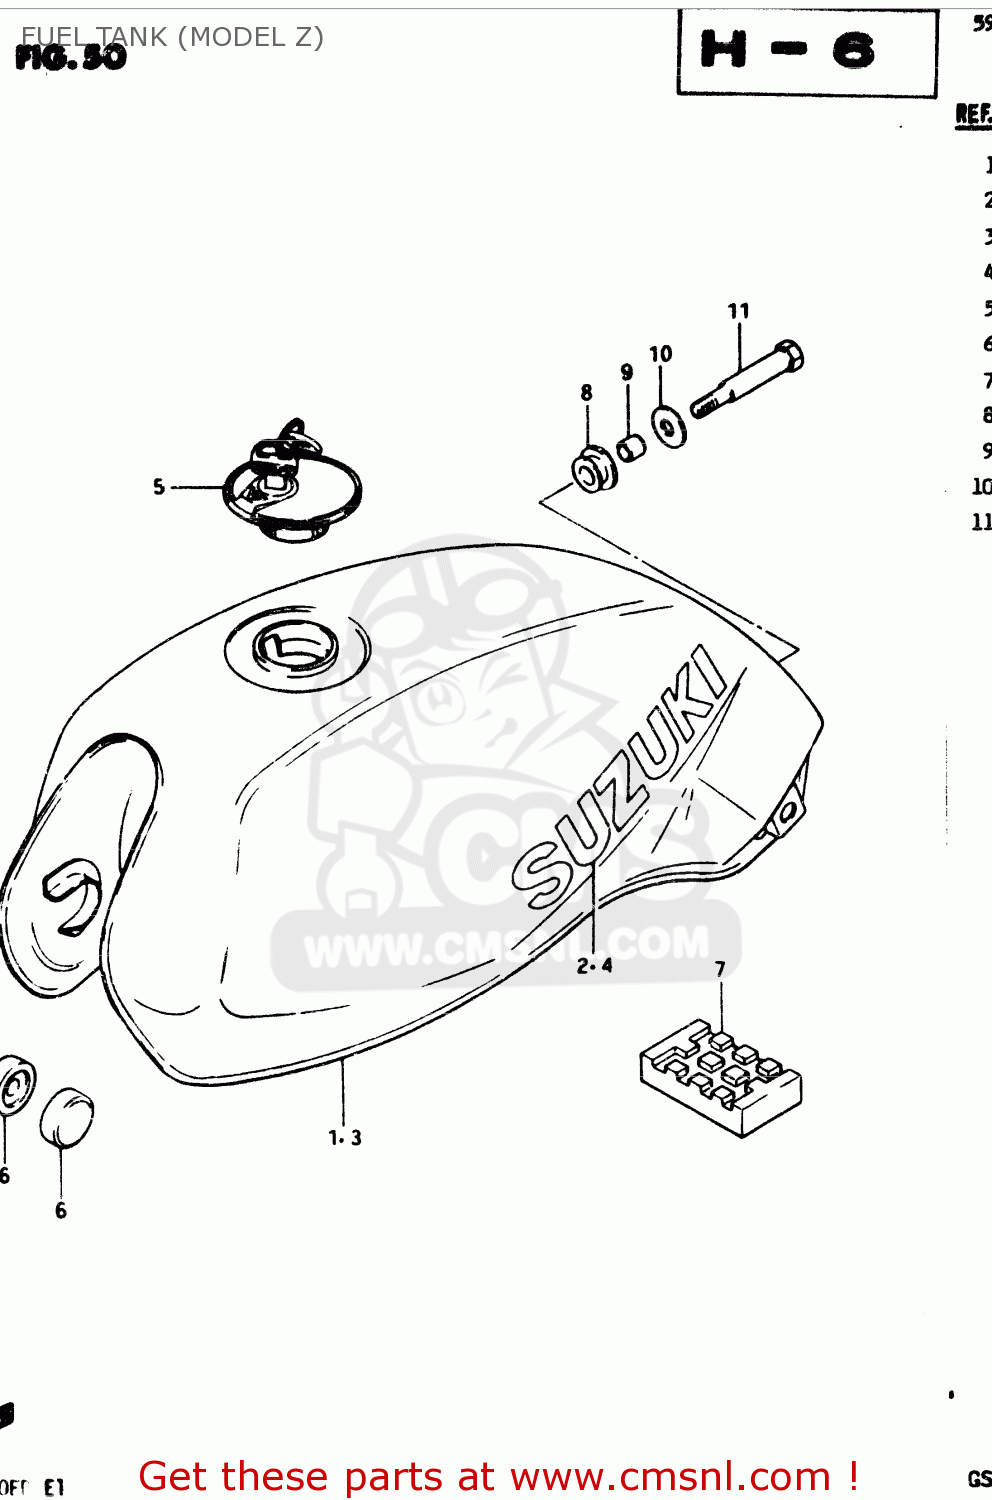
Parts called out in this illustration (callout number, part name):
1	TANK, FUEL (RED)
2	EMBLEM(SILVER)
3	TANK, FUEL (SILVER)
4	EMBLEM(ORANGE)
5	CAP SET,FUEL TANK
6	CUSHION
7	CUSHION,FUEL TANK CTR
8	CUSHION
9	SPACER (6.8X10X10)
10	WASHER (6.5X29X1.6)
11	BOLT(6X60)
